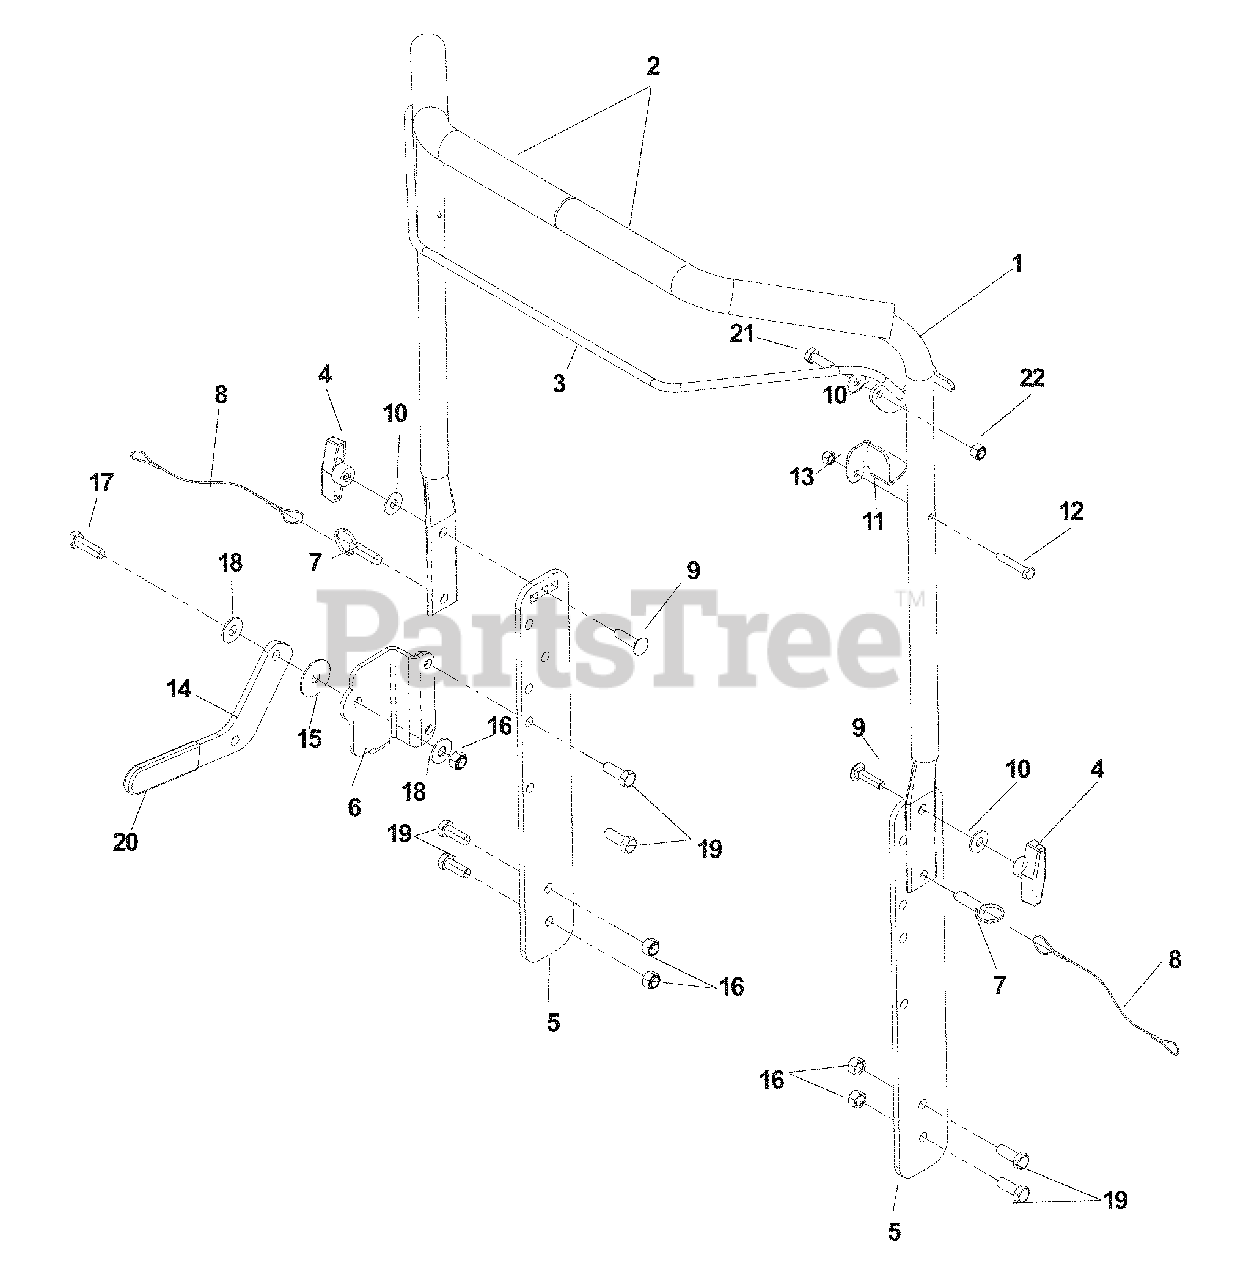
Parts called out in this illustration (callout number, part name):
5	HANDLE SIDE
9	RHSNB 5/16C X 1 1/4
10	WASHER, 5/16, FLAT
12	HCS 1/4C X 1 1/2
13	NUT, 1/4C, NYLOC
15	WASHER, FRICTION
16	NUT, 3/8C, NYLOC
17	HCS 3/8C X 1 1/4
18	WASHER, 3/8, FLAT
19	HCS 3/8C X 1
20	ADJ. LEVER GRIP
21	HCS 5/16C X 1
22	NUT, 5/16C, NYLOC
